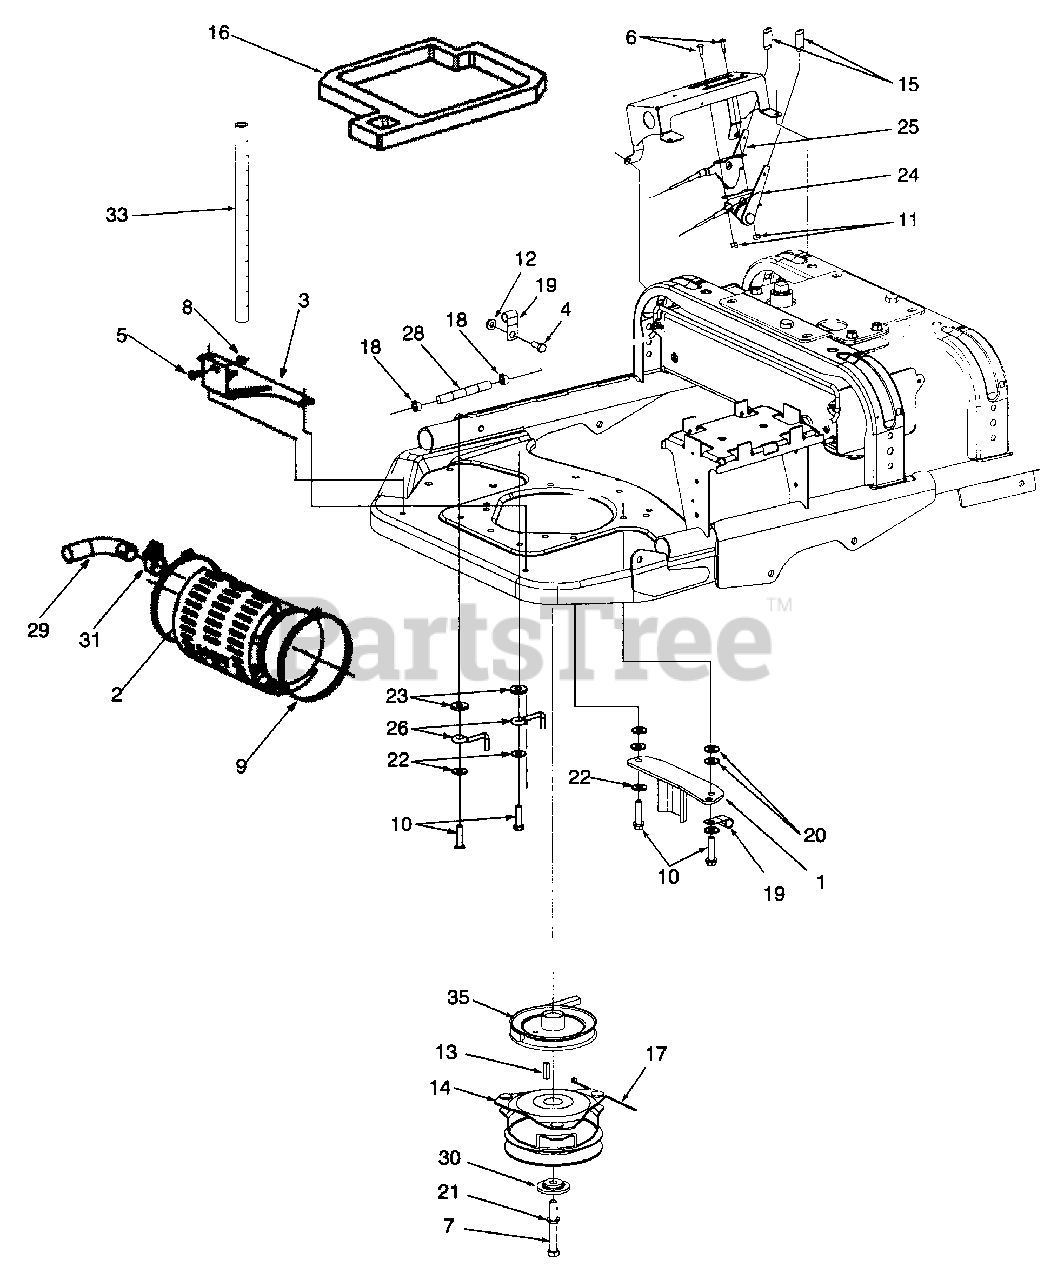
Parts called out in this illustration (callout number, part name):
4	Screw, Hex Cap 3/8-16 x .75
5	Screw, Hex Cap 5/16-18 x .75
6	Screw, Phil. Pan Hd,10-24 x .75
7	Screw, Hex Cap Gr 8.8 M10-1.50 x .75mm
8	Nut, Hex Flanged Lock 5/16-18
9	Clamp, Adj. 6.50 / 5.63 Dia.
10	Screw, Hex Cap, M8-1.25 x 35 Gr 8.8
11	Nut, Hex, #10-24
12	Nut, Hex Flange Lock, 3/8-16
13	Key, Square, 1/4 x 1.0
14	Clutch Assembly, PTO
16	Seal Ring, Foam Gasket
20	Washer, Flat
21	Washer, Lock, 7/16
22	Washer, Bell, .340 x .872 x .06
23	Washer, Flat, .385 x 1.0 x .135
24	Cable, Choke Control
25	Cable, Throttle Control
26	Rod, Rear Belt Retainer
28	Fuel Line Hose 33" Length
29	Tube, Kawasaki Muffler Exhaust
30	Spacer, Clutch
31	Clamp, Muffler Exhaust Tube
33	Extension Hose, Oil Drain 13" Lg
35	Pulley, Transmission Drive
